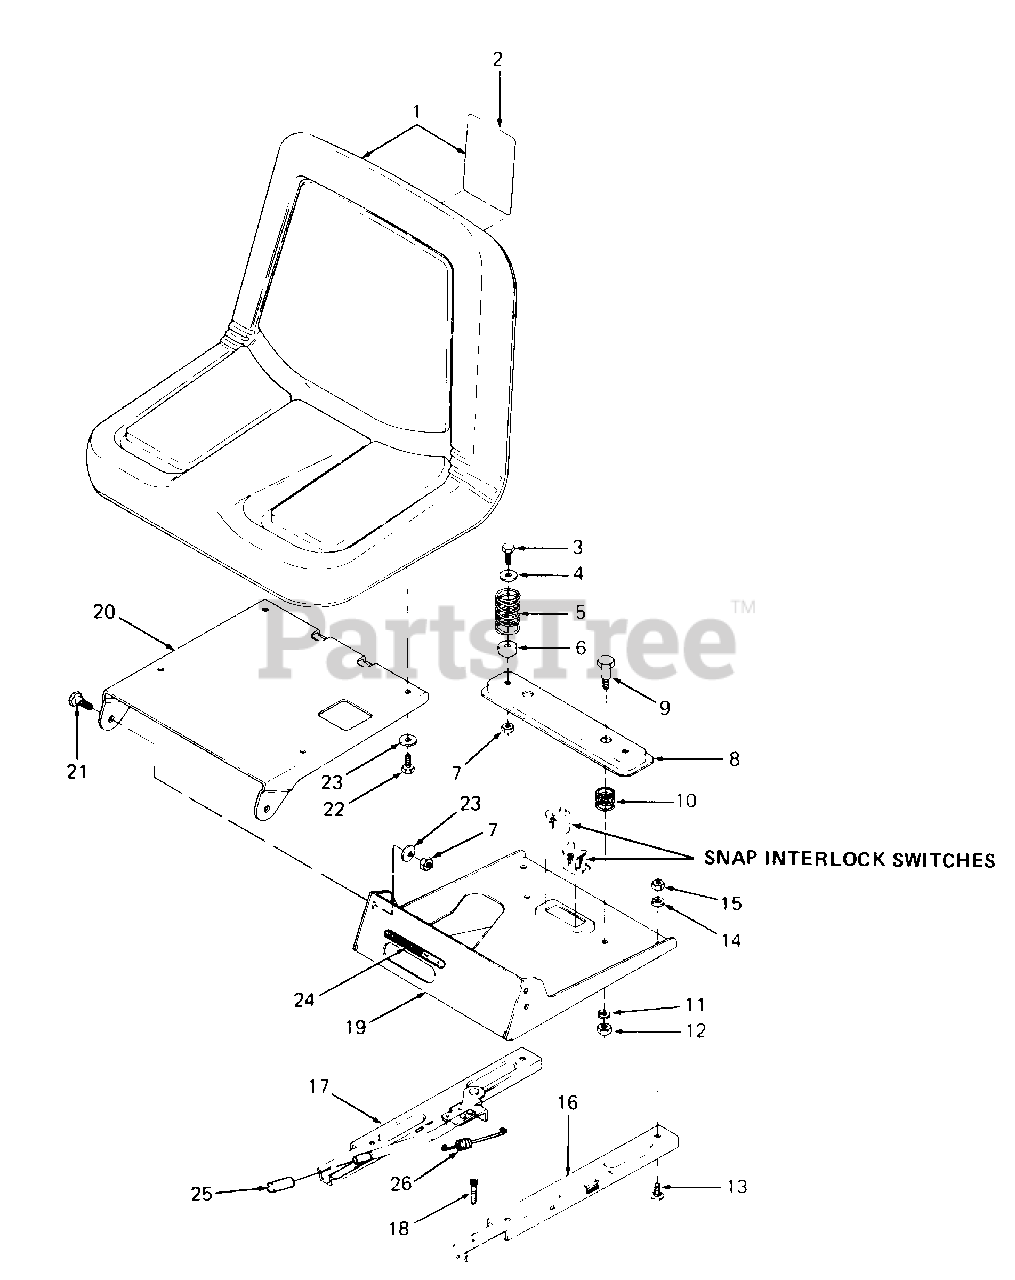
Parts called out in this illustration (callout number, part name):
1	Seat w/Graphic
2	Graphic, Caution
3	Screw, Hex Cap, 5/16-18 X .88 Lg GR5
4	Washer, Flat, .344 X .875 X .06 Thk
5	Spring, Comp, 1.28 OD X 2.18 Lg
6	Bushing, .930 OD X.50 Lg
7	Nut, Hex Center Lock, 5/16-18 GR5
10	Spring, Comp, 1.00 OD X.86 Lg
11	Washer, Lock, 3/8
12	Nut, Hex, 3/8-16 GR5
13	Bolt, Sht Nk Carriage, 5/16-18 X.62 Lg
14	Washer, Lock, 5/16
15	Nut, Hex, 5/16-18 GR5
16	Slide, Seat - LH
17	Adjuster, Manual Seat - RH
18	Screw, Socket Hd Cap, 5/16-18 X 1.00 Lg
22	Screw, Hex Cap, 5/16-18 X .75 Lg GRS
23	Washer, Bell, .345 X .88 X .060 Thk
24	Label, Seat Adjustment
25	Cover, Handle
